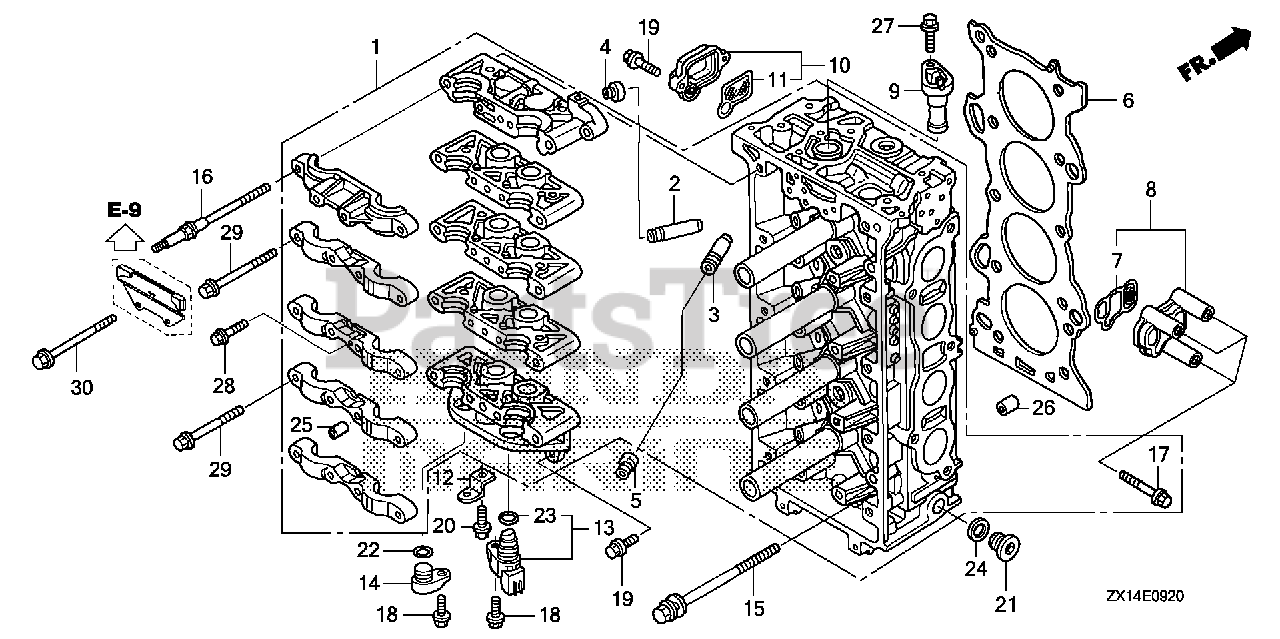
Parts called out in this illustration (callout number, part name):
1	CYLINDER HEAD KIT *NH8* (DARK GRAY)
1	CYLINDER HEAD KIT *N
2	GUIDE, VALVE (OVER SIZE)
3	GUIDE, EX. VALVE (OVER SIZE)
4	SEAL A, VALVE STEM (NOK)
5	SEAL B, VALVE STEM (NOK)
6	GASKET, CYLINDER HEAD
7	FILTER ASSY., SPOOL VALVE
8	COVER ASSY., OIL PASSAGE
9	PLUG, VTC HOLE
10	STRAINER ASSY., VTC *NH8* (DARK GRAY)
11	FILTER ASSY., VTC
12	BRACKET F, CLIP
13	SENSOR ASSY., TDC
14	PLUG, TDC HOLE
15	BOLT-WASHER (11X155)
16	BOLT A, HEAD COVER
17	BOLT, FLANGE (6X52)
18	BOLT, FLANGE (6X16)
19	BOLT, FLANGE (6X20)
20	BOLT, FLANGE (6X14)
21	BOLT, SEALING (20MM)
22	O-RING (15X1.9)
23	O-RING (15X1.9)
24	WASHER, DRAIN PLUG (20MM)
25	PIN A, DOWEL (10X16)
26	PIN A, DOWEL (14X20)
27	BOLT, FLANGE (6X20)
28	BOLT, FLANGE (6X32)
29	BOLT, FLANGE (8X90)
30	BOLT, FLANGE (8X110)
